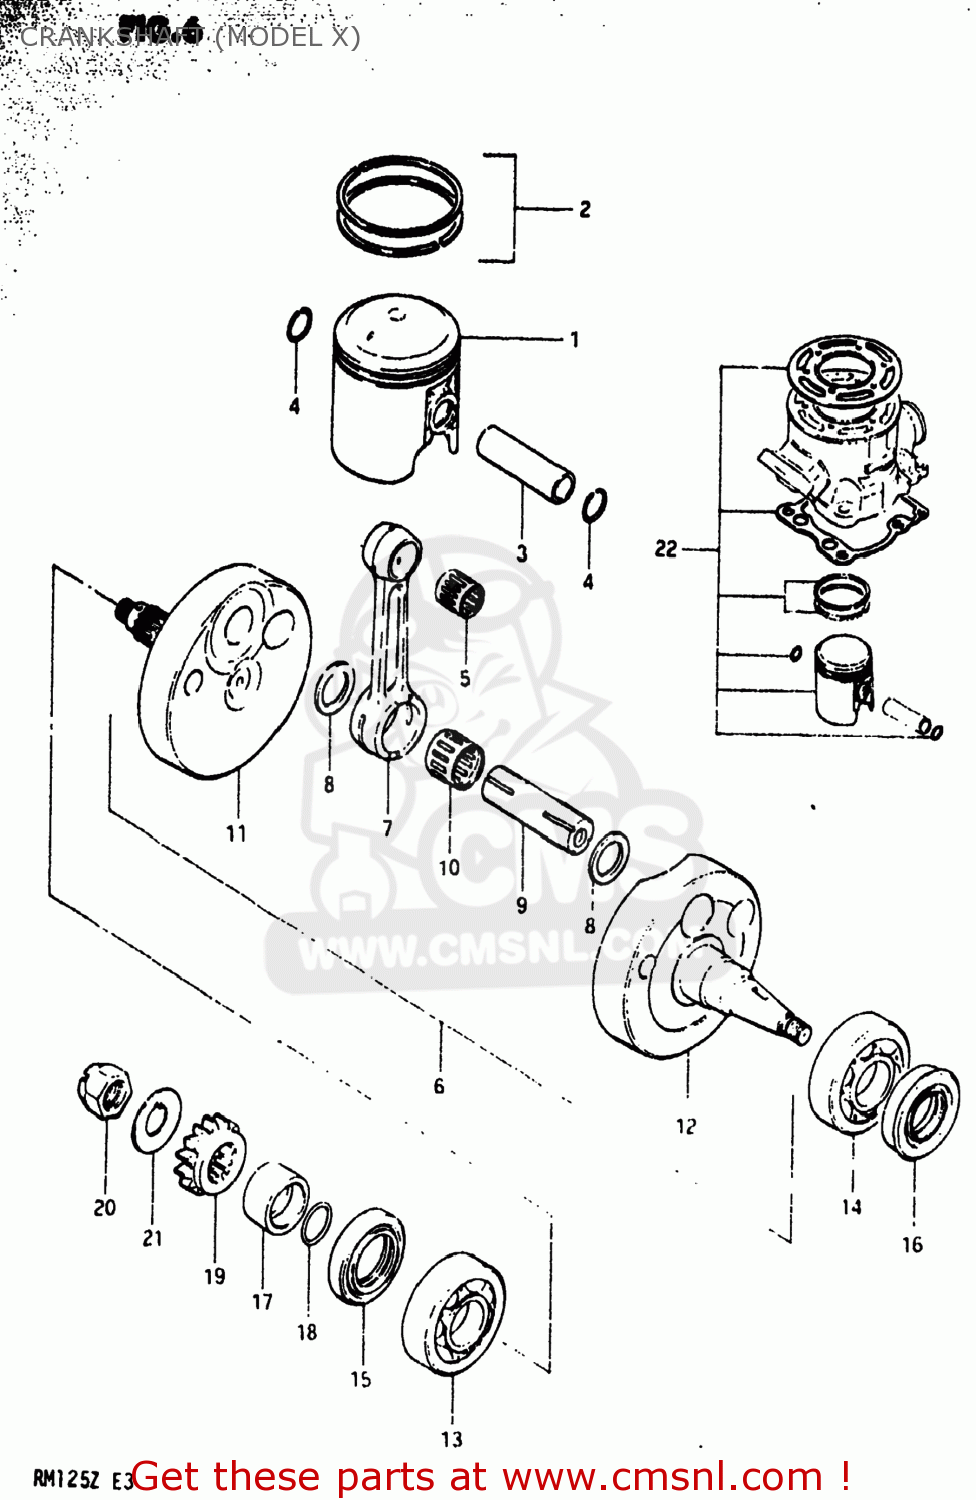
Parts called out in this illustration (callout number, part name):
1	PISTON
2	RING SET,PISTON
3	PIN,PISTON
4	RING,SNAP 14MM
5	BEARING
6	CRANKSHAFT ASSEMBLY
7	CONNECTING ROD
8	WASHER(19X32X1)
9	PIN,CRANK
10	BEARING(19X25X16)
11	CRANKSHAFT,RIGHT
12	CRANKSHAFT,LEFT
13	BEARING
14	BEARING
15	SEAL,OIL(28X40X8)
16	SEAL,OIL(19.6X37X8)
17	SPACER,PRIMARY DRIVE GEAR
18	O RING(D:2.4,ID:19.8)
19	GEAR,PRIMARY DRIVE
20	NUT
21	WASHER
22	PISTON SET
